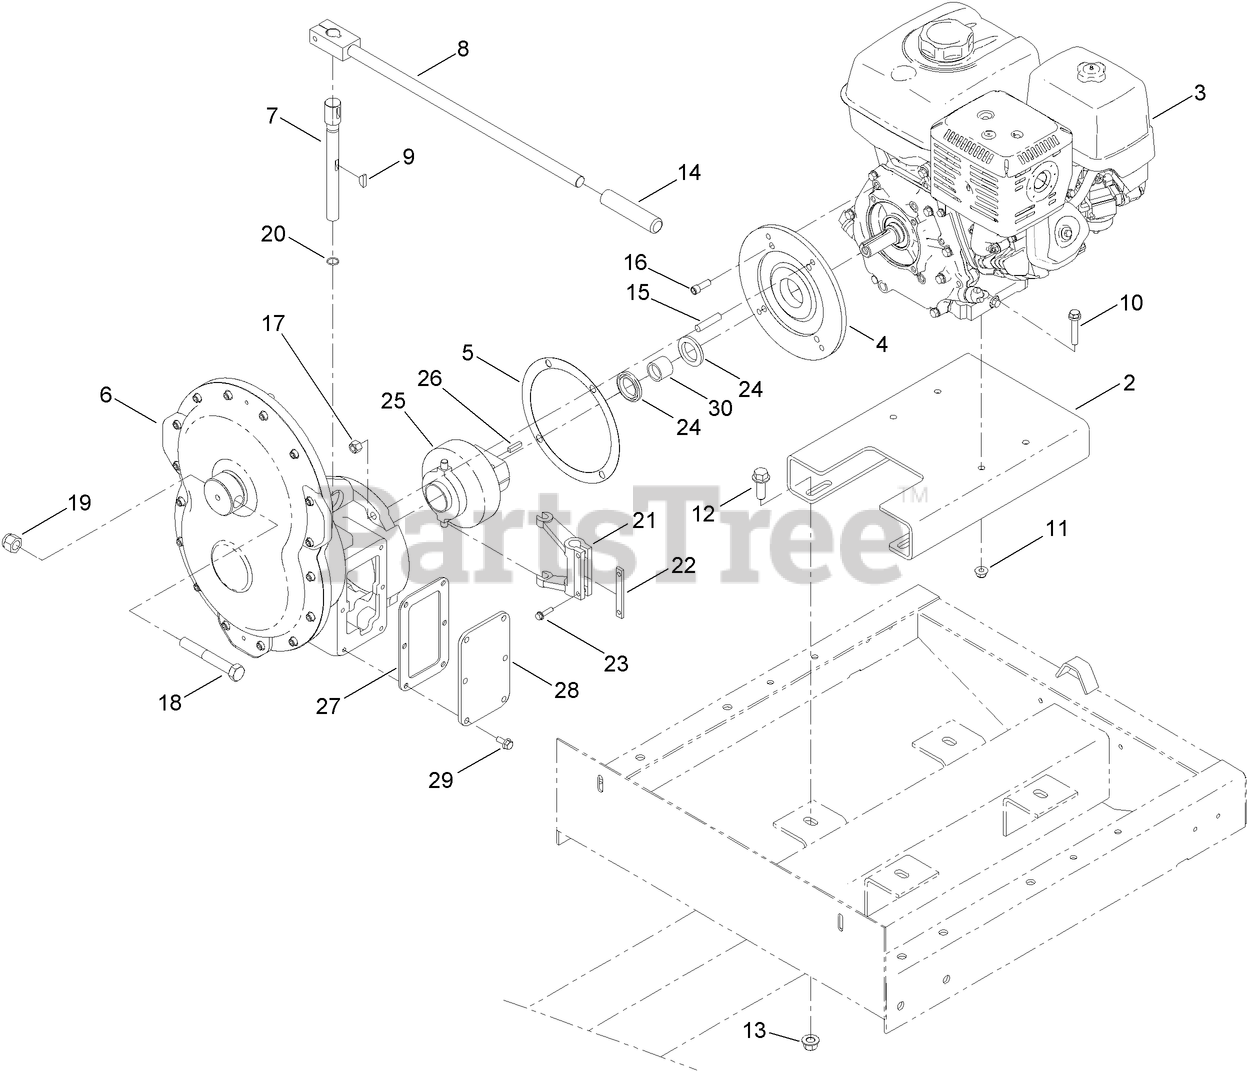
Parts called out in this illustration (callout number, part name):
2	BASE-MOTOR
3	ENGINE-HONDA, GX340
4	ADAPTOR-ENGINE
5	GASKET-ADAPTER, ENGINE
6	GEARCASE ASM
7	SHAFT-CLUTCH
8	HANDLE-CLUTCH
10	SCREW-HHF
11	NUT-HF, NI
12	SCREW-HHF
13	NUT-LOCK
14	GRIP-FLEX
16	SCREW-HSH
17	NUT-LOCK, NI
18	SCREW-HH
19	NUT-LOCK, NI
20	O-Ring
21	FORK-CLUTCH
22	SPACER-FORK, CLUTCH
23	SCREW-HHF
24	SEAL-SHAFT
25	CLUTCH-DISCONNECT, SLIP
27	GASKET-ACCESS, CLUTCH
28	COVER-ACCESS, CLUTCH
29	SCREW-HHF
30	BUSHING-SHAFT
